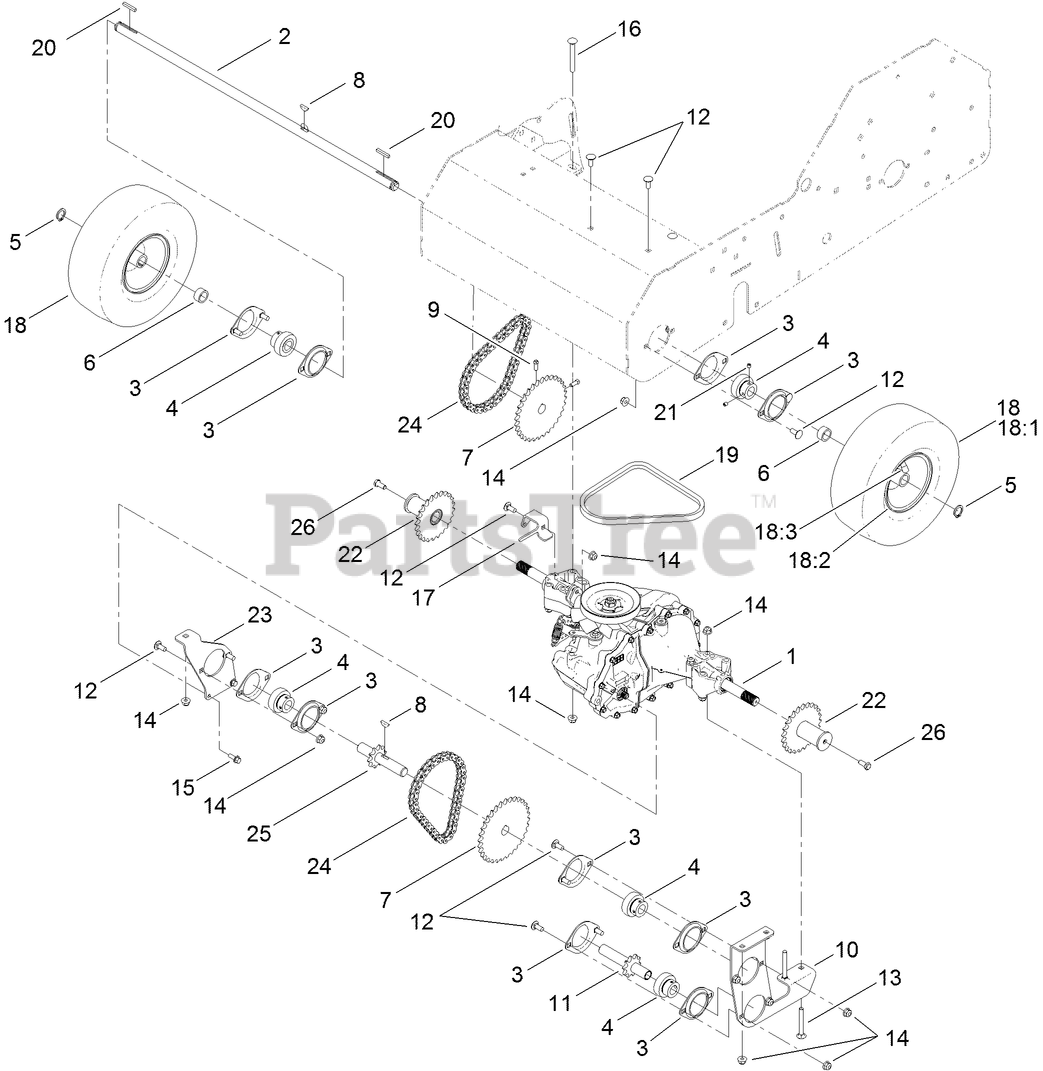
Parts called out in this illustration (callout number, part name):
1	TRANSAXLE ASM
2	SHAFT-WHEEL
3	FLANGE-BEARING
4	BEARING-LOCK, COLLAR
5	RING-RETAINING
6	SPACER-WHEEL
7	SPROCKET
8	KEY-WOODRUFF
9	SCREW-SET
10	PLATE-BEARING
11	SHAFT-OUTPUT
12	SCREW-CARR
13	SCREW-CARR
14	NUT-HF, NI
15	SCREW-HHF
16	SCREW-CARR
17	ANGLE-CONTROL
18	WHEEL ASM
18:2	WHEEL-RIM
18:3	VALVE
19	BELT-DRIVE
20	KEY-SQUARE
21	SCREW-SET, HSH
22	SPROCKET ASM
23	BRACKET-SUPPORT, SHAFT
24	CHAIN-DRIVE WHEEL
25	SHAFT-JACK
26	SCREW-HH
